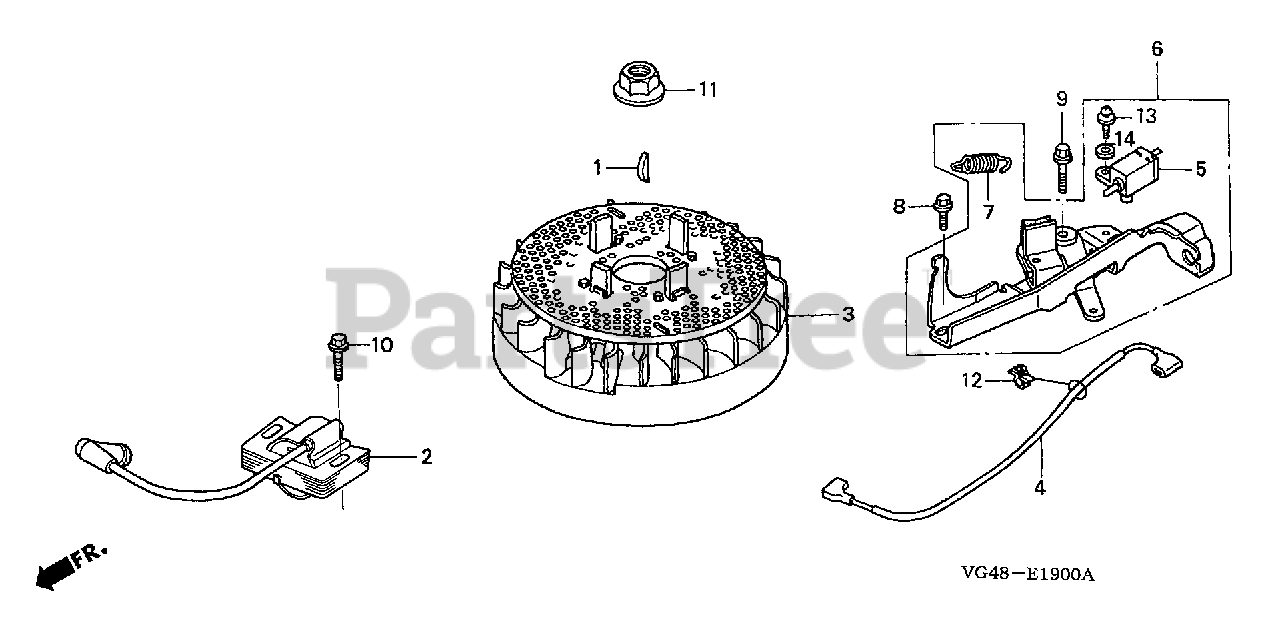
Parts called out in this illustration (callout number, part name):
1	KEY, SPECIAL WOODRUFF (25X18)
2	COIL ASSY., IGNITION (USE FOR F/W OF TEC) (TEC)
2	COIL ASSY., IGNITION (PHELON) (USE FOR F/W OF PHELON)
2	COIL ASSY., IGNITION (PHELON)
3	FLYWHEEL ASSY. (TEC) (USE FOR IGN. COIL OF TEC)
3	FLYWHEEL ASSY. (PHELON) (USE FOR IGN. COIL OF PHELON)
4	WIRE, STOP SWITCH
5	SWITCH ASSY., ENGINE STOP (N.C)
6	BRAKE ASSY.
7	SPRING, BRAKE LEVER
8	BOLT, FLANGE (6X14) (CT200)
9	BOLT, FLANGE (6X23) (CT200)
10	BOLT, FLANGE (6X20) (CT200)
11	NUT, SPECIAL (14MM)
12	CLIP A, CABLE (3.8MM BLACK) (NIFCO)
13	SCREW-WASHER (4X12)
14	WASHER, PLAIN (4MM)
